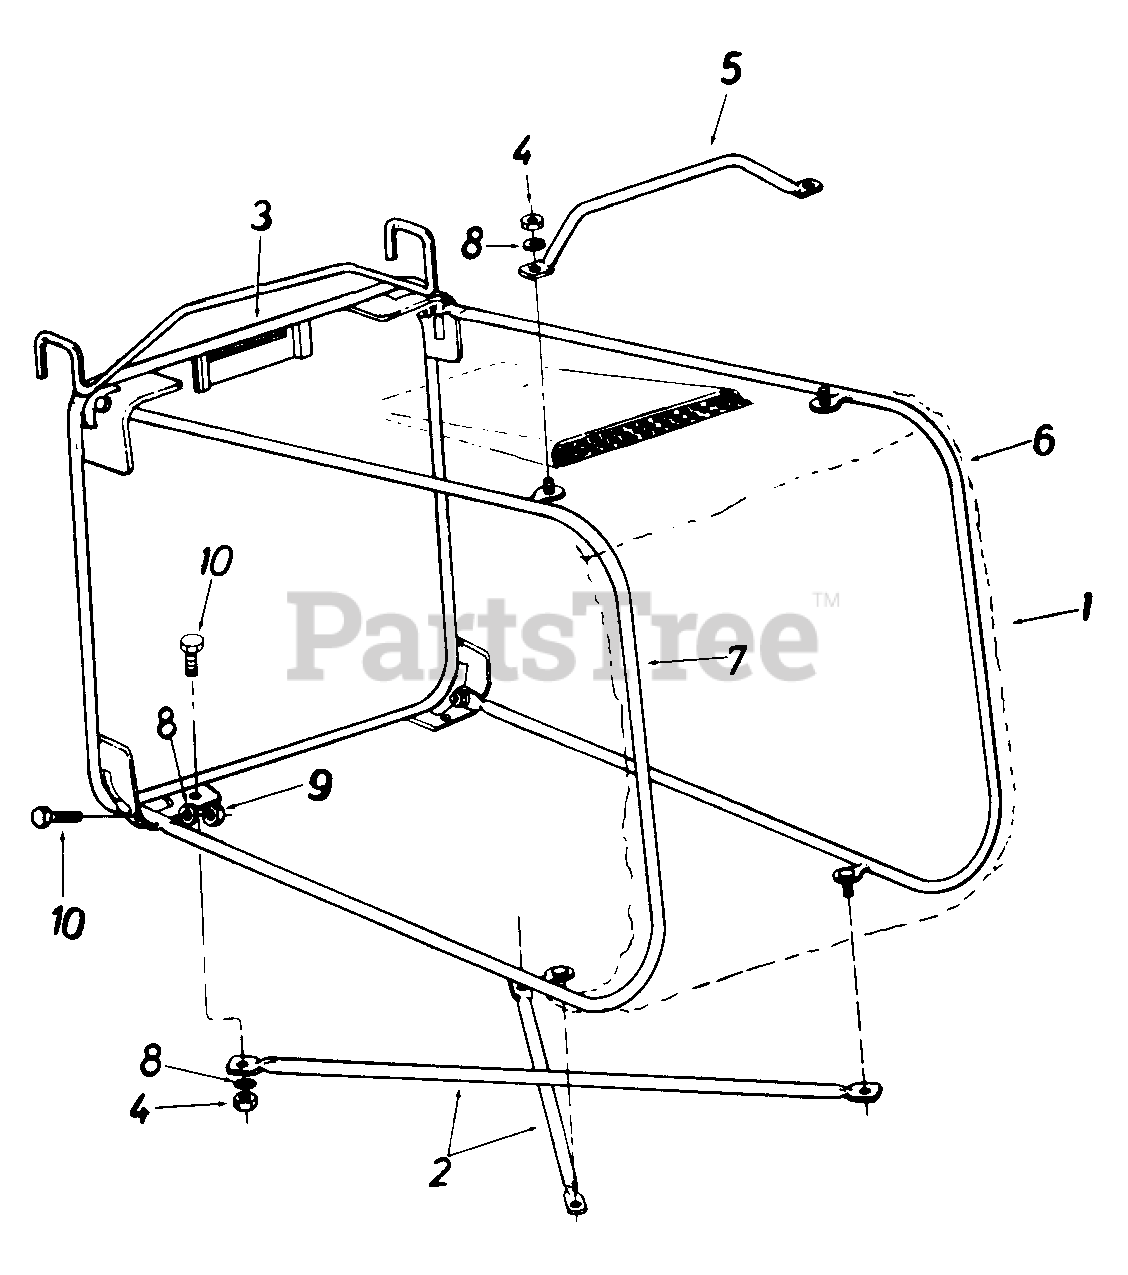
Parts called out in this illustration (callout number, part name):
1	Grass Catcher Bag
2	Bottom Cross Brace
3	Grass Catcher Frame Ass'y.
4	Hex Cent. L-Nut 1/4-20 Thd.
5	Grass Catcher Handle
9	Hex Cent. L.-Nut 1/4-20 Thd.
10	Hex Bolt 1/4-20 x .62" Lg.*
